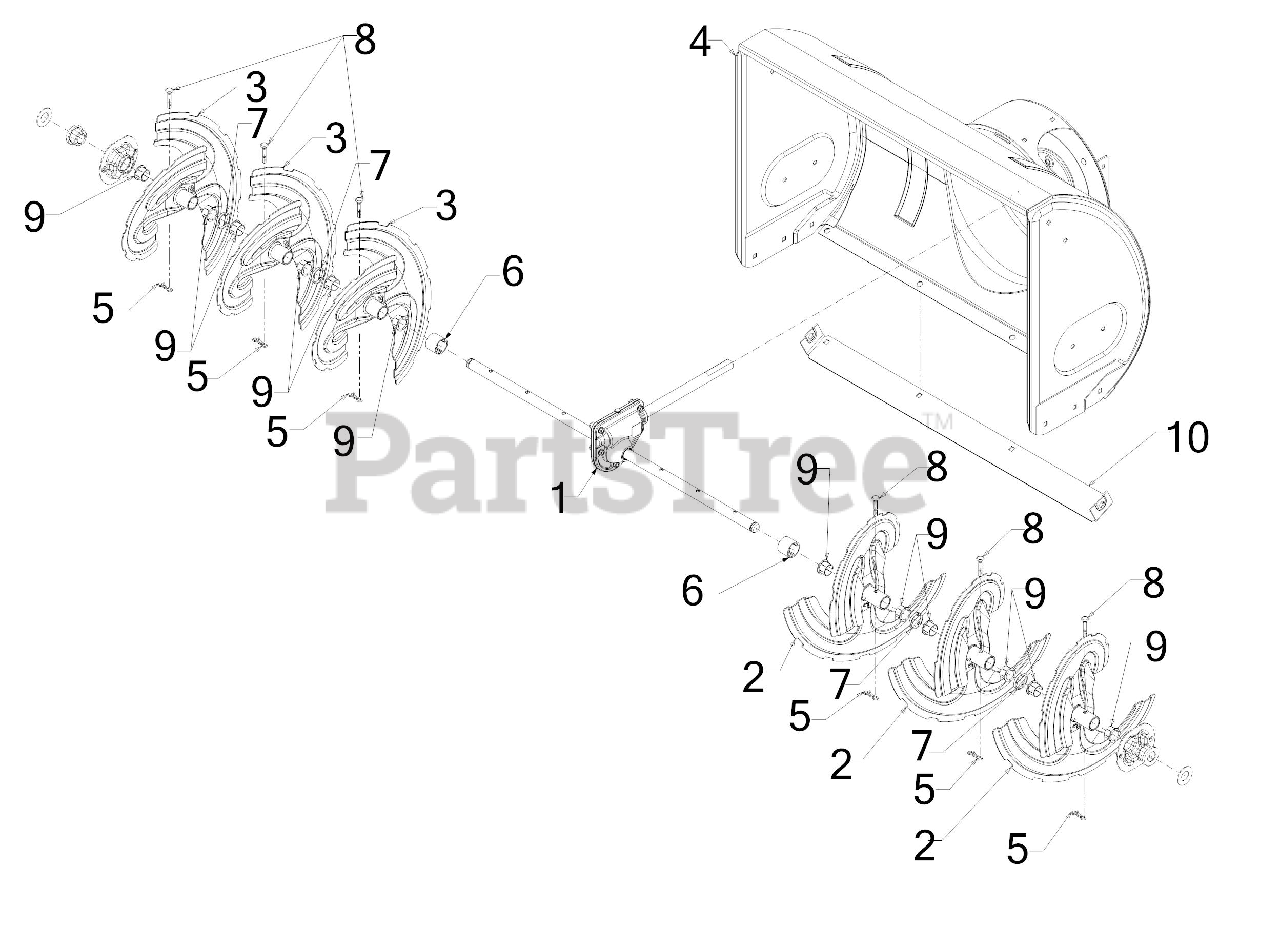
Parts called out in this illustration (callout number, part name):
1	30" GEARBOX ASSEMBLY
2	AUGER ASSEMBLY (LH)
3	AUGER ASSEMBLY (RH)
4	30" AUGER HOUSING
5	BOW TIE COTTER PIN 1/4-5/16
6	SPACER 1.25OD x .75ID X1.00 LG
7	SPCR 1.25 OD x 75IDX2.00LG
8	SHEAR PIN .25 x 1.50 GR2
9	FLANGE BUSHING
10	30" SHAVE PLATE
